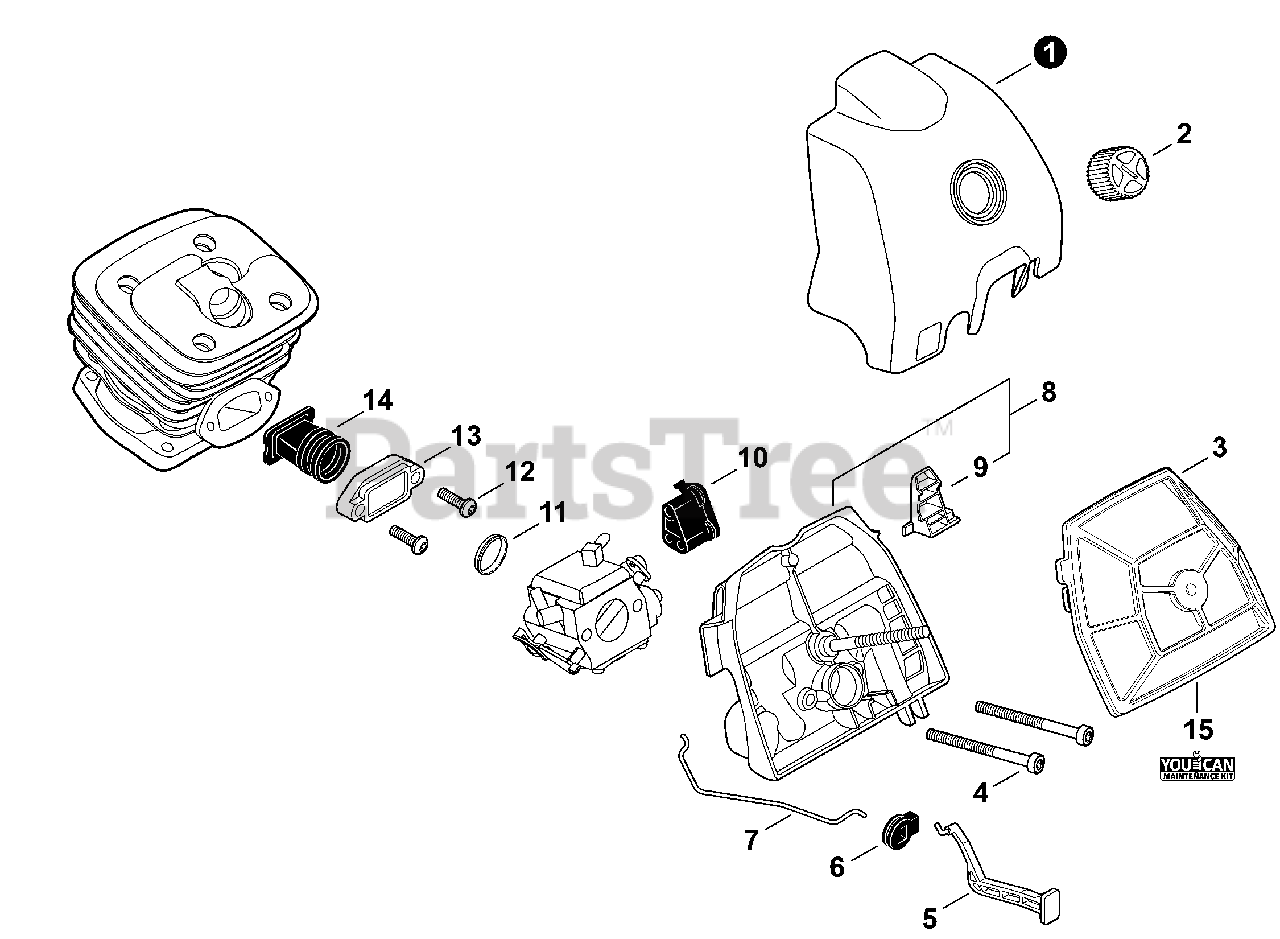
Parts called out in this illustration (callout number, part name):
1	COVER, AIR FILTER
2	KNOB, AIR FILTER COVER
3	FILTER ASSY, AIR
4	BOLT, TORX 5×50
5	ROD, CHOKE
6	GROMMET, CHOKE
7	ROD, THROTTLE
8	CASE, AIR FILTER
9	SHUTTER, AIR
10	GROMMET, NEEDLE
11	COLLAR 18.6×20.4×4
12	BOLT, TORX 5×16
13	HOLDER, BELLOWS
14	BELLOWS, INTAKE
15	TUNE-UP KIT - YOUCAN™
